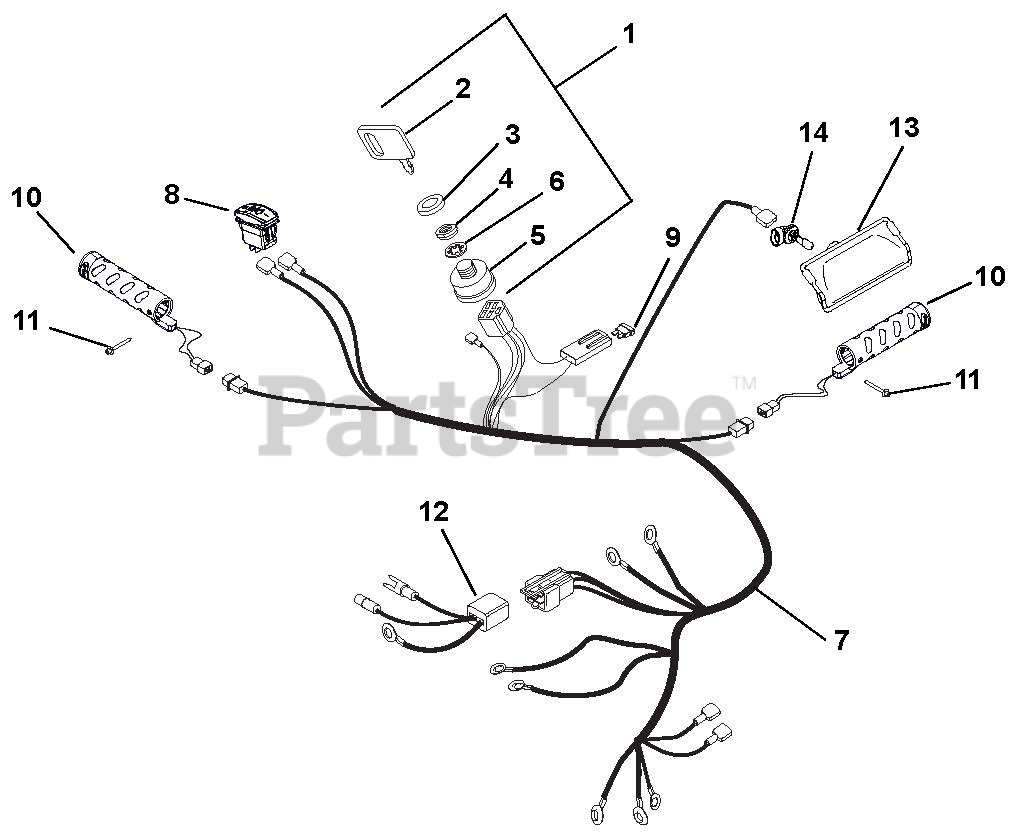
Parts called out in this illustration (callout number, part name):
1	SWITCH ASSEMBLY
2	KEY -W/CAP
3	CAP - IGNITION SWITCH
4	NUT-PANEL .625-32 GRECO
5	IGNITION SWITCH ASSEMBLY
6	WSHR-LK-INT .625X.045 YWZC
7	HARNESS,BRUSH-LT,HW,12V
8	SWITCH,ROCKER SPST-ON/OFF
9	FUSE, 15 AMP.
10	GRIP,HEATED HANDLE-GRAY
11	RVT-POP #43 .125X.313 STL ZINC
12	HARNESS ADAPTER, SUBARU
13	HEADLIGHT ASY, HOLO 15W 2 SHOT
14	BULB, LIGHT-HALOGEN 15 WATT
